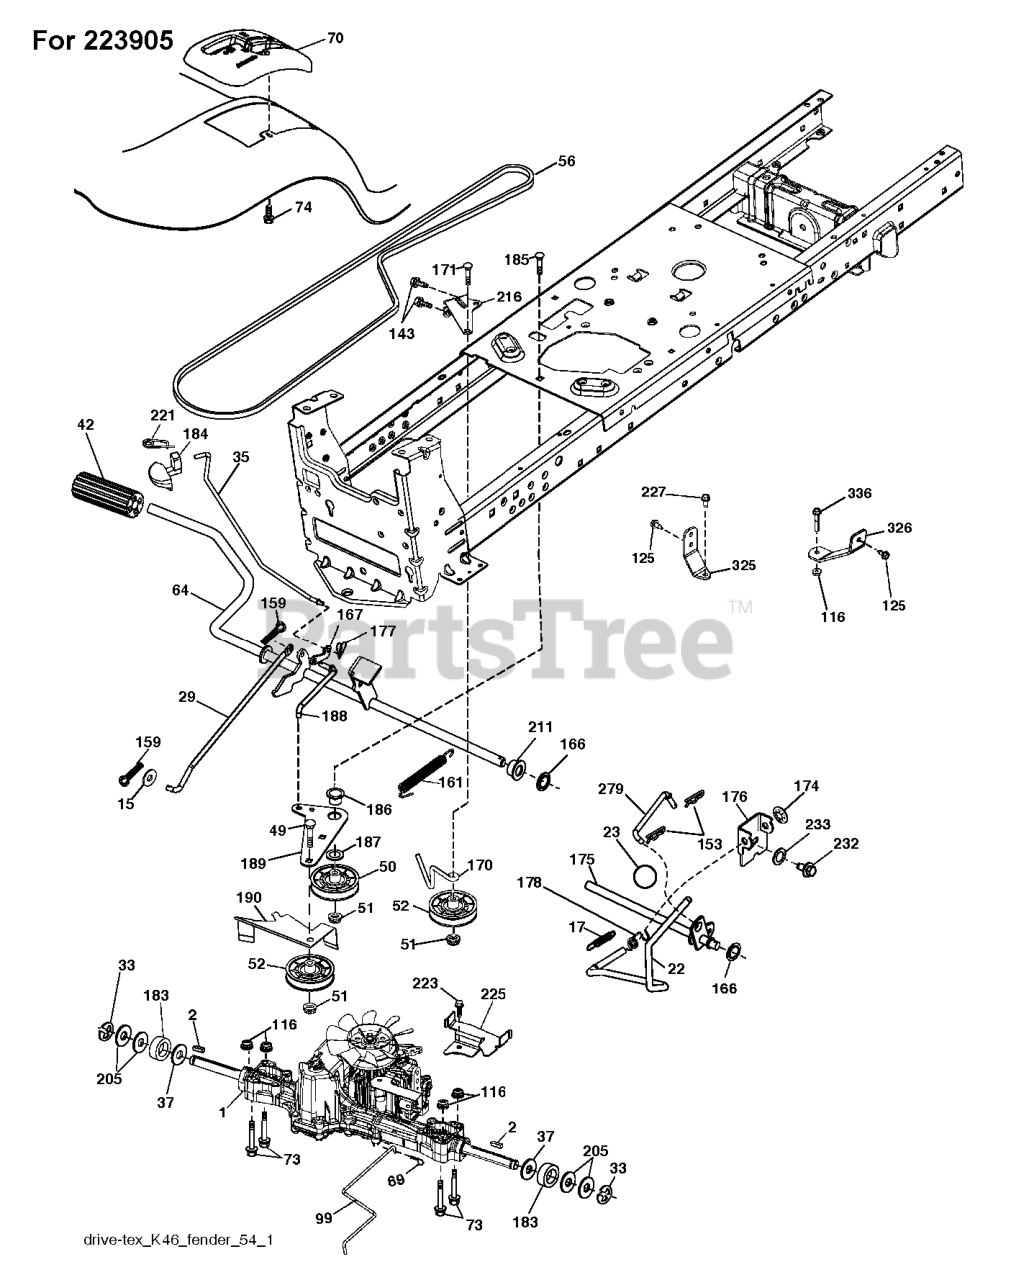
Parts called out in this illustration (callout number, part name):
2	SQUARE KEY
15	WASHER PLAIN WASHER 3/8 X 0.08
17	SPRING.BRAKE.K46.GREEN
22	ROD.SHIFT.FENDER.TLT.2006
23	KNOB.DELUXE.(PISTOL.GRIP).BLAC
29	ROD.BRAKE.K46
35	ROD ROD.PARKINGBRAKE.GT.HUSQ/P
37	WASHER.HARDENED
42	PEDAL COVER
50	IDLER.FLAT.910.OFFSET
51	NUT LOCK FLG 3/8-16 UNC
52	IDLER.V-GROOVE.910.OFFSET
64	SHAFT.ASM.PEDAL.BRAKE.
69	HAIRPIN.SOFT.ZINC.059X1.125
70	CONSOLE.SHIFT.STL.HYD.TEX.GREY
99	ARM.PIVOTING.TCRD.GEN2.5.BAGGE
125	SCREW
153	RETAINER M
161	SPRING, RETURN LT
166	NUT.PUSH.625
167	LATCH.BRAKE.SPRING
170	KEEPER.V-IDLER.CENTER.
174	NUT.PUSH.500.2006
175	SHAFT ASM SHIFT
176	ARM.CLEVIS.ROD.SHIFT
177	PIN COTTER;LOCKING;BOWTIE;1IN
178	SPRING.SHIFT.GT2006
183	SPACER AXLE
184	HANDLE.PARKING.BRAKE.H (BLK)
186	SPACER.RETAINER
188	LINK.CLUTCH.GROUND DRIVE.LONG
189	BELLCRANK.GROUND.DRIVE.TEX.
190	KEEPER.BELLCRANK.DRIVE
211	BUSHING.SHAFT.BRAKE.HAND
216	BRACKET.PULLEY.IDLER.W/TEX
221	RETAINER.SPRING.CLIP.H
225	KEEPER.BELT.TRANSAXLE.K46
279	LINK.SHIFT.T/A.K46.FEND.TX
325	BRACKET.TRQ.STP.46.20".TIRE.LH
326	BRCKT.PNT.TRQ.STP.46.20TIRE.RH
